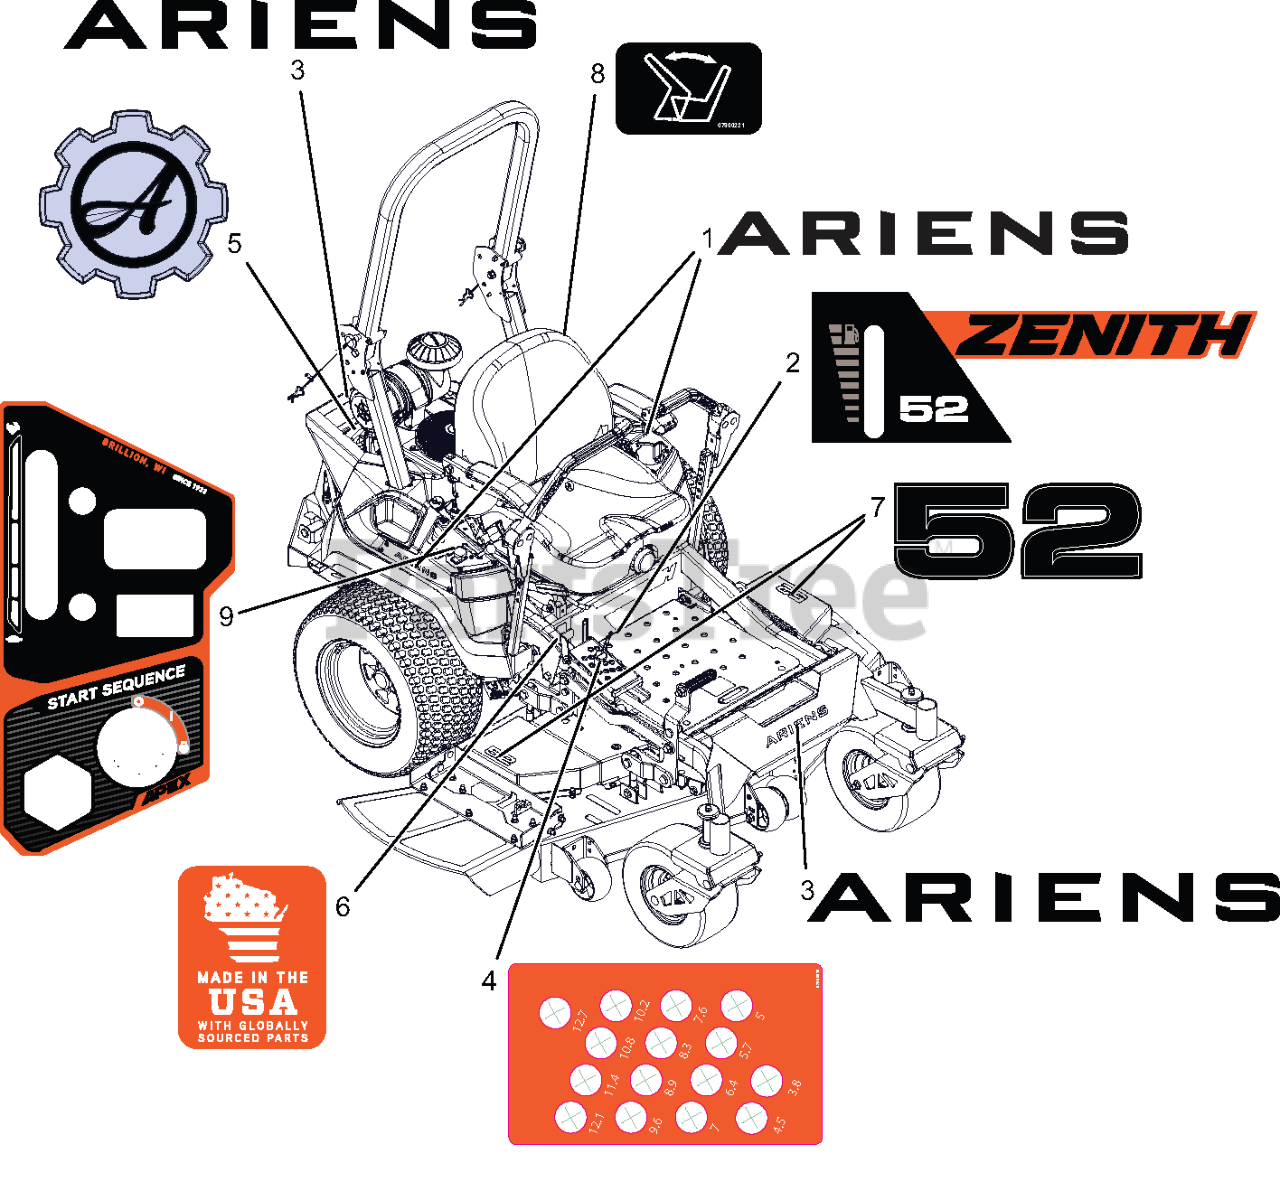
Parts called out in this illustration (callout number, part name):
1	DECAL- ARIENS 6.000" BLACK
2	DECAL- ZENITH 52 KICKPLATE
3	DECAL- ARIENS 9.625" BLACK
4	DECAL, APEX HOC METRIC
5	DECAL- ARIENS GEAR BADGE
6	DECAL- MADE IN USA
7	DECAL- DECK 52
8	DECAL - SEAT RELEASE
9	DECAL- DASH -APEX & ZENITH
